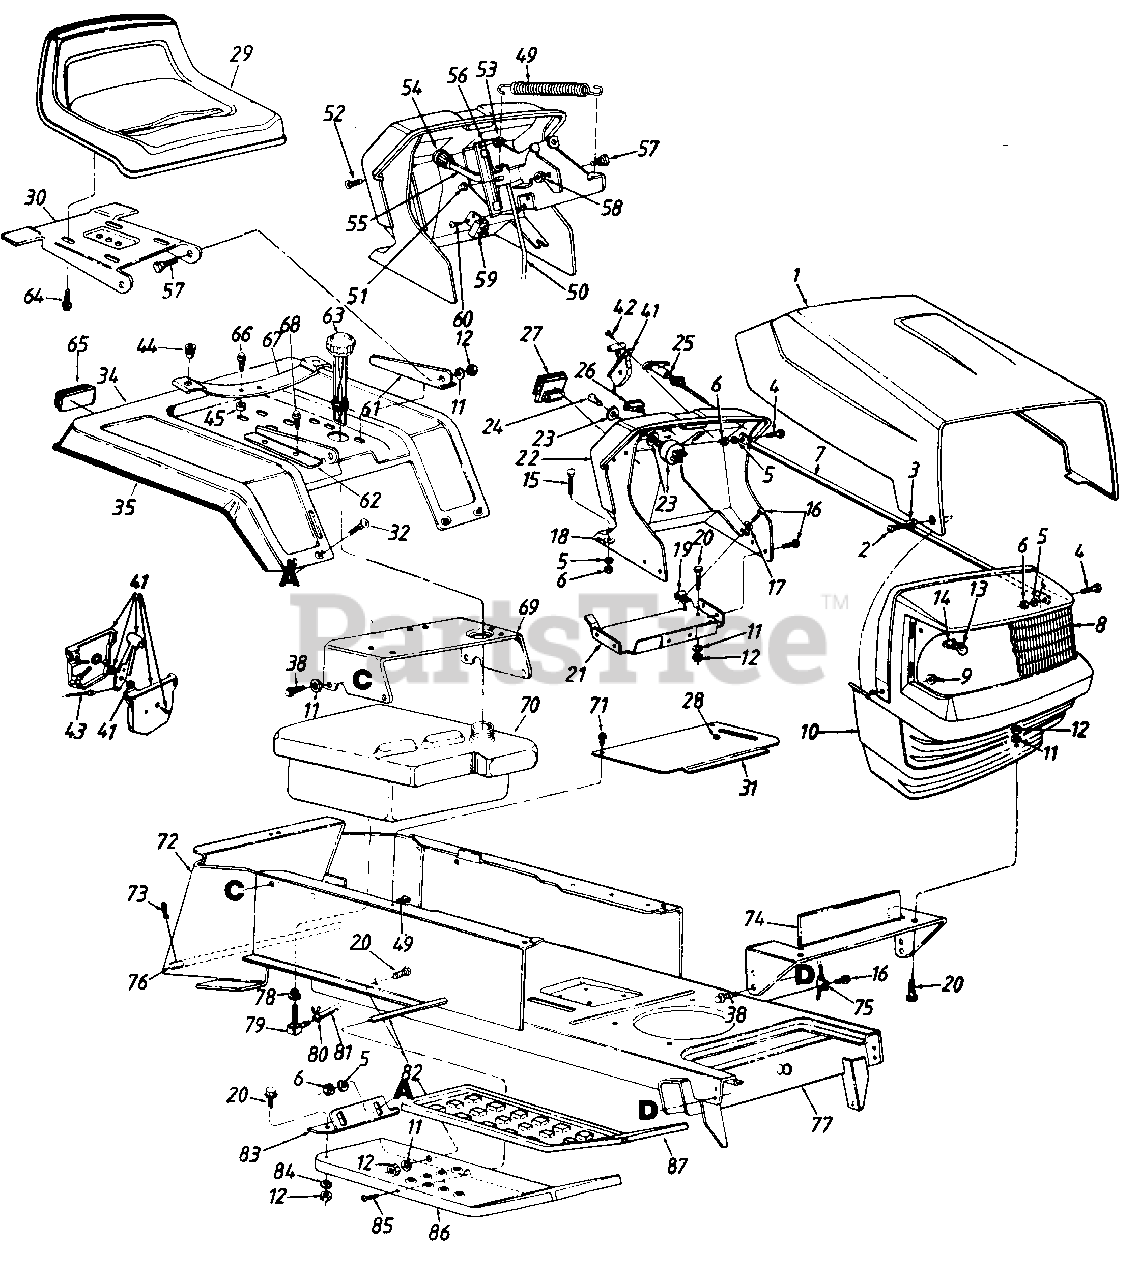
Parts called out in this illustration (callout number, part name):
1	N Hood
2	Shld. Bolt .375" Dia. x .125" Lg.
3	Spr. Wash. .265" I.D. x .562" O.D.
4	Hex Bolt 1/4-20 x .62" Lg.
5	L-Wash. 1/4" I.D.
6	Hex Nut 1/4-20 Thd.
7	N Grille Support Rod
8	N Headlight Lens
9	Flange L-Nut 1/4-28 Thd.
10	N Grille
11	L-Wash. 5/16" I.D.
12	Hex Nut 5/16-18 Thd.
13	Lamp
14	Socket
15	Carriage Bolt 1/4-20 x 1.0" Lg.
16	Hex (Wash. Hd. TT-Tap Scr. 1/4-20 x .5" Lg.)
17	Fl-Wash. .281" I.D. x .73" O.D.
18	Bolt Retainer 1/4" I.D.
19	Speed Nut 1/4-20 Thd.
20	Hex Bolt 5/16-18 x .75" Lg.
23	Ignition Switch
24	Ignition Key
25	Choke Control
26	Light Switch
27	Ammeter
28	Snap Bushing
29	Seat Ass'y.
30	Seat Pivot Bracket
31	Shift Cover
32	Carriage Bolt 1/4-20 x .5" Lg.
38	Hex Wash. Hd. AB-Tap Scr. 5/16 x .75" Lg.
41	Throttle Box Ass'y.
42	Truss Mach. AB-Tap Scr. #10 x .5" Lg.
43	Throttle Control Wire
44	Grommet
45	Spacer.38" I.D.
49	N Ext. Spring 5.06" Lg.
50	N Deck Control Rod
51	Speed Nut 1/4" Rod
52	Truss Mach. Scr. 1/4-20 x .5 Lg.
53	Hex Sems Nut 1/4-20 Thd.
54	PTO Knob
55	N PTO Lever
56	N PTO Bracket
57	Shld. Bolt .437" Dia. x .162"
58	Hex L-Nut 5/16-18 Thd.
59	N Safety Switch
60	N Hex Wash. Hd. B-Tap Scr. #10 x .38" Lg.
61	Seat Bracket L.H.
62	Seat Bracket R.H.
63	Gas Cap w/Gauge
64	Hex Wash. Hd. AB-Tap Scr. 3/8 x .75" Lg.
65	Reflector
66	Hex Tap Scr. 5/16-18 x 1.25"Lg.
67	Seat Spring
68	Hex Wash. Hd. Self-Tap Scr. 5/16-18 x .5" Lg.
69	Seat Mounting Channel
70	Fuel Tank
71	Truss Mach. B-Tap Scr. #10 x .5" Lg.
74	Grille Mounting Bracket
75	Battery Hose Clamp
76	Hitch Rod
77	N Lower Frame Ass'y.
78	Bushing
79	90ø Nipple
80	Hose Clamp
81	Fuel Line 46" Lg.
82	Running Board Rod
85	Truss Mach. Scr. 5/16-18 x .75" Lg.
